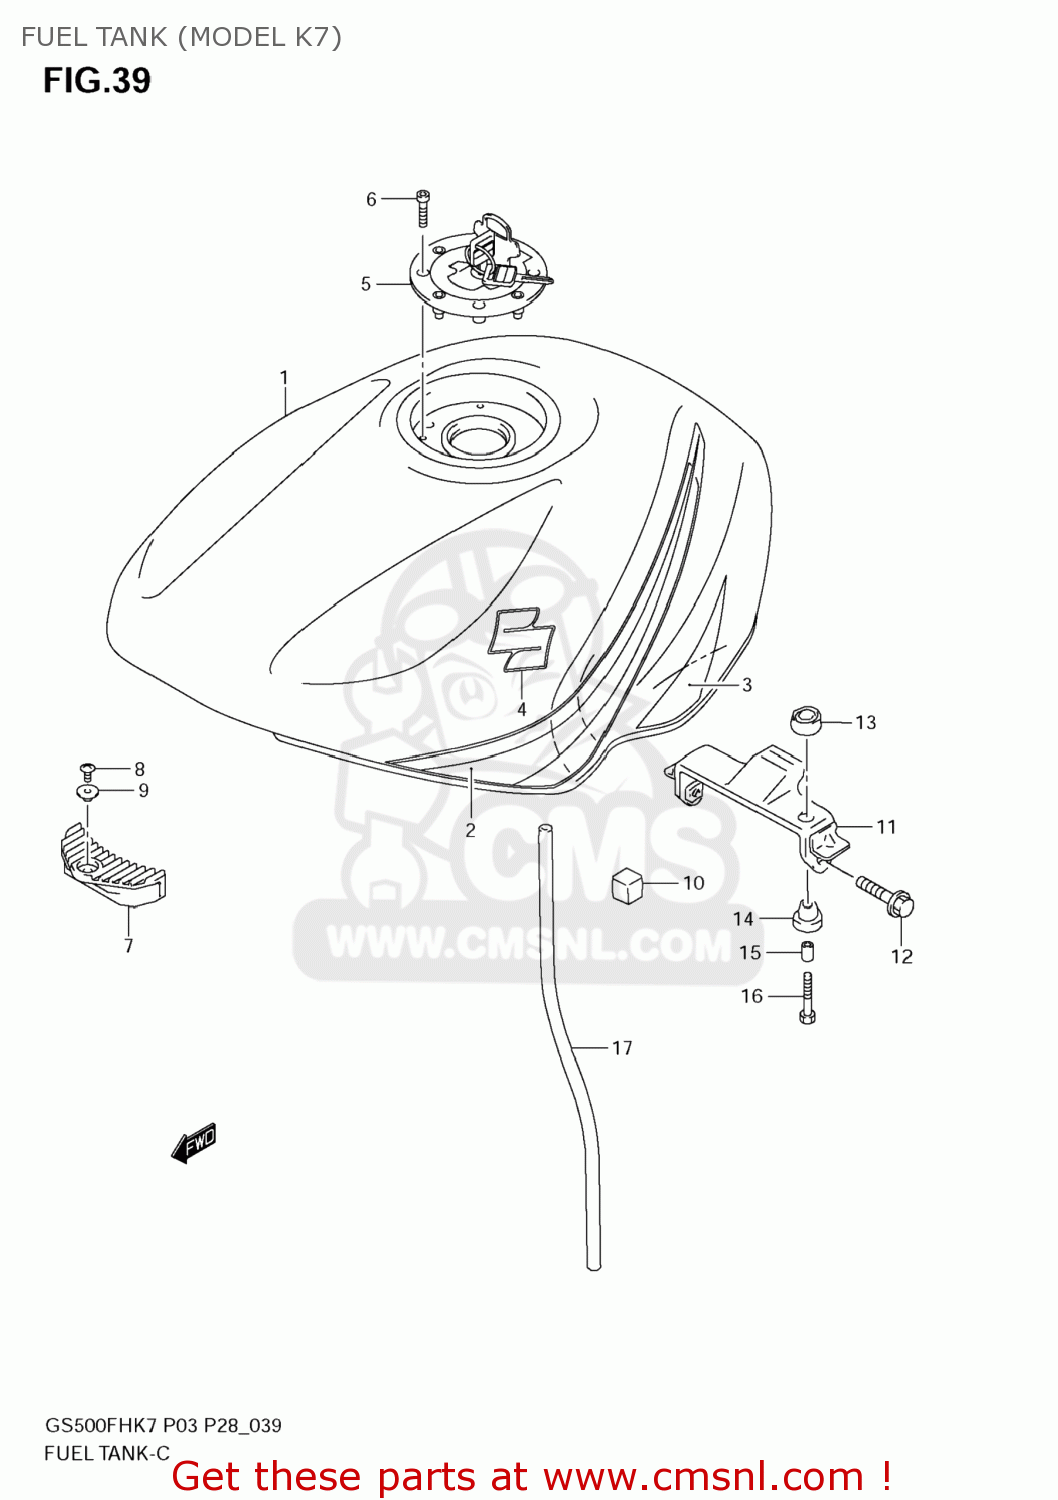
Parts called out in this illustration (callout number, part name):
1	TANK ASSY,FUEL(GRAY)
2	TAPE SET,FUEL TANK
3	TAPE SET,FUEL TANK LWR
4	EMBLEM,S
5	CAP SET,FUEL TANK
6	BOLT(5X20)
7	CUSHION,FUEL TANK FR
8	SCREW, THROTTLE CABLE
9	WASHER
10	CUSHION,FUEL TANK SIDE
11	BRACKET, REAR
12	BOLT
13	CUSHION
14	CUSHION
15	SPACER(6.5X9X18)
16	BOLT(6X30)
17	HOSE, DRAIN
